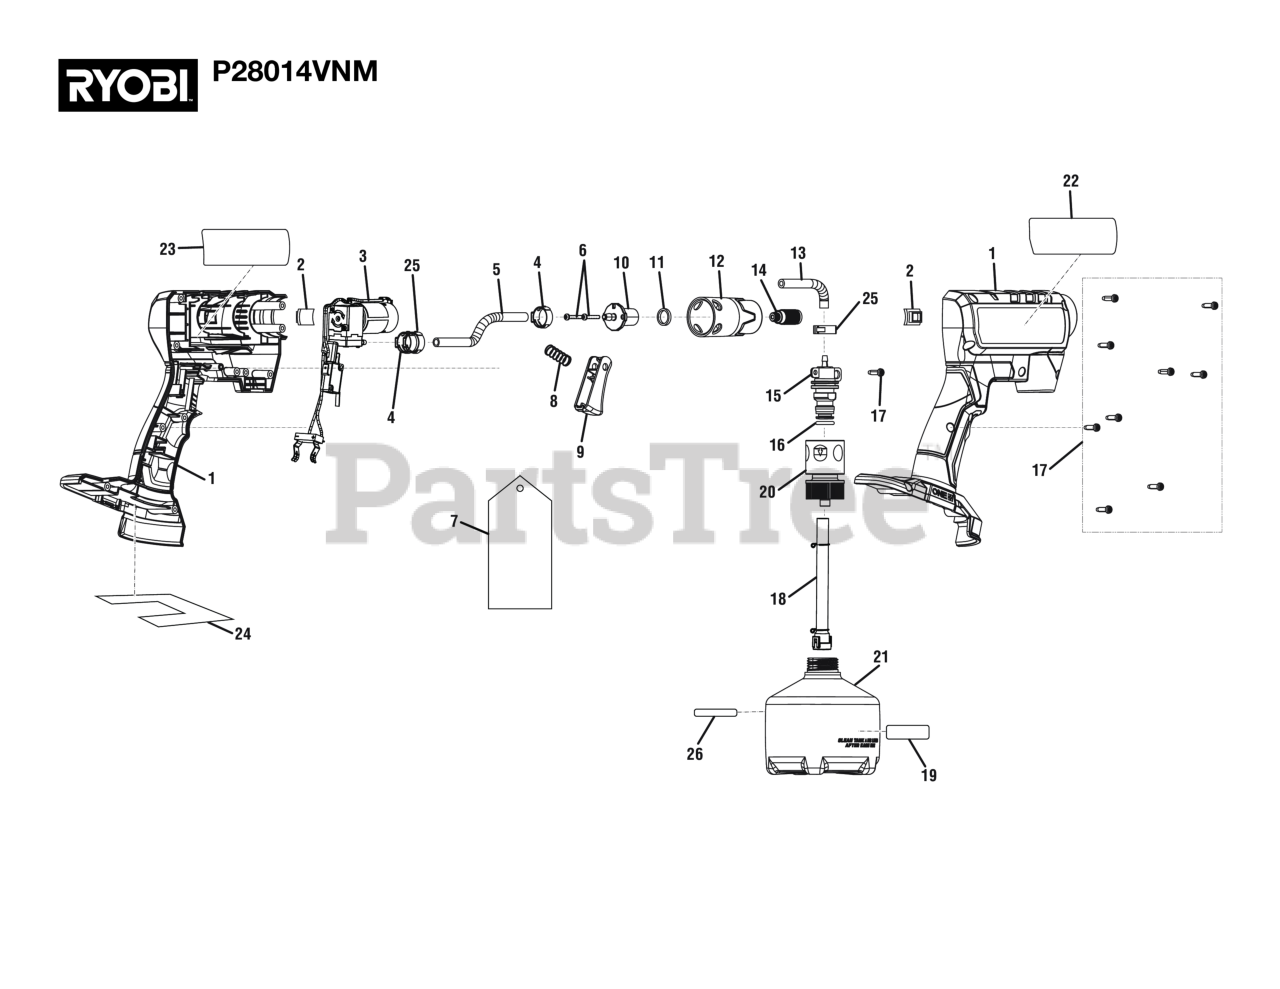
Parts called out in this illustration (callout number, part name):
1	Motor Housing Assembly (Inc. Key Nos. 22-24)
2	Rubber Pad
3	Pump and Switch Assembly
4	Hose Clamp
5	Hose (Pump Outlet)
6	Screw (M3 x 17.5 mm)
7	Instructions Tag/SP Warnings
8	Compression Spring
10	One-Way Valve
11	Back-Up Oring
12	Outlet Tube Housing
13	Hose (Pump Inlet)
16	O-Ring (ID11.3 x CS2.5)
17	Screw (M4 x 14 mm, T15 Torx Pan Hd.))
18	Filter Assembly
20	Shutoff Valve
21	Tank Assembly (Inc. Key Nos. 19 & 26)
22	EN/FR Icon Warning Label
23	Logo Label
24	Data Label
25	Hose Clamp
26	Max Fill Tank Label
